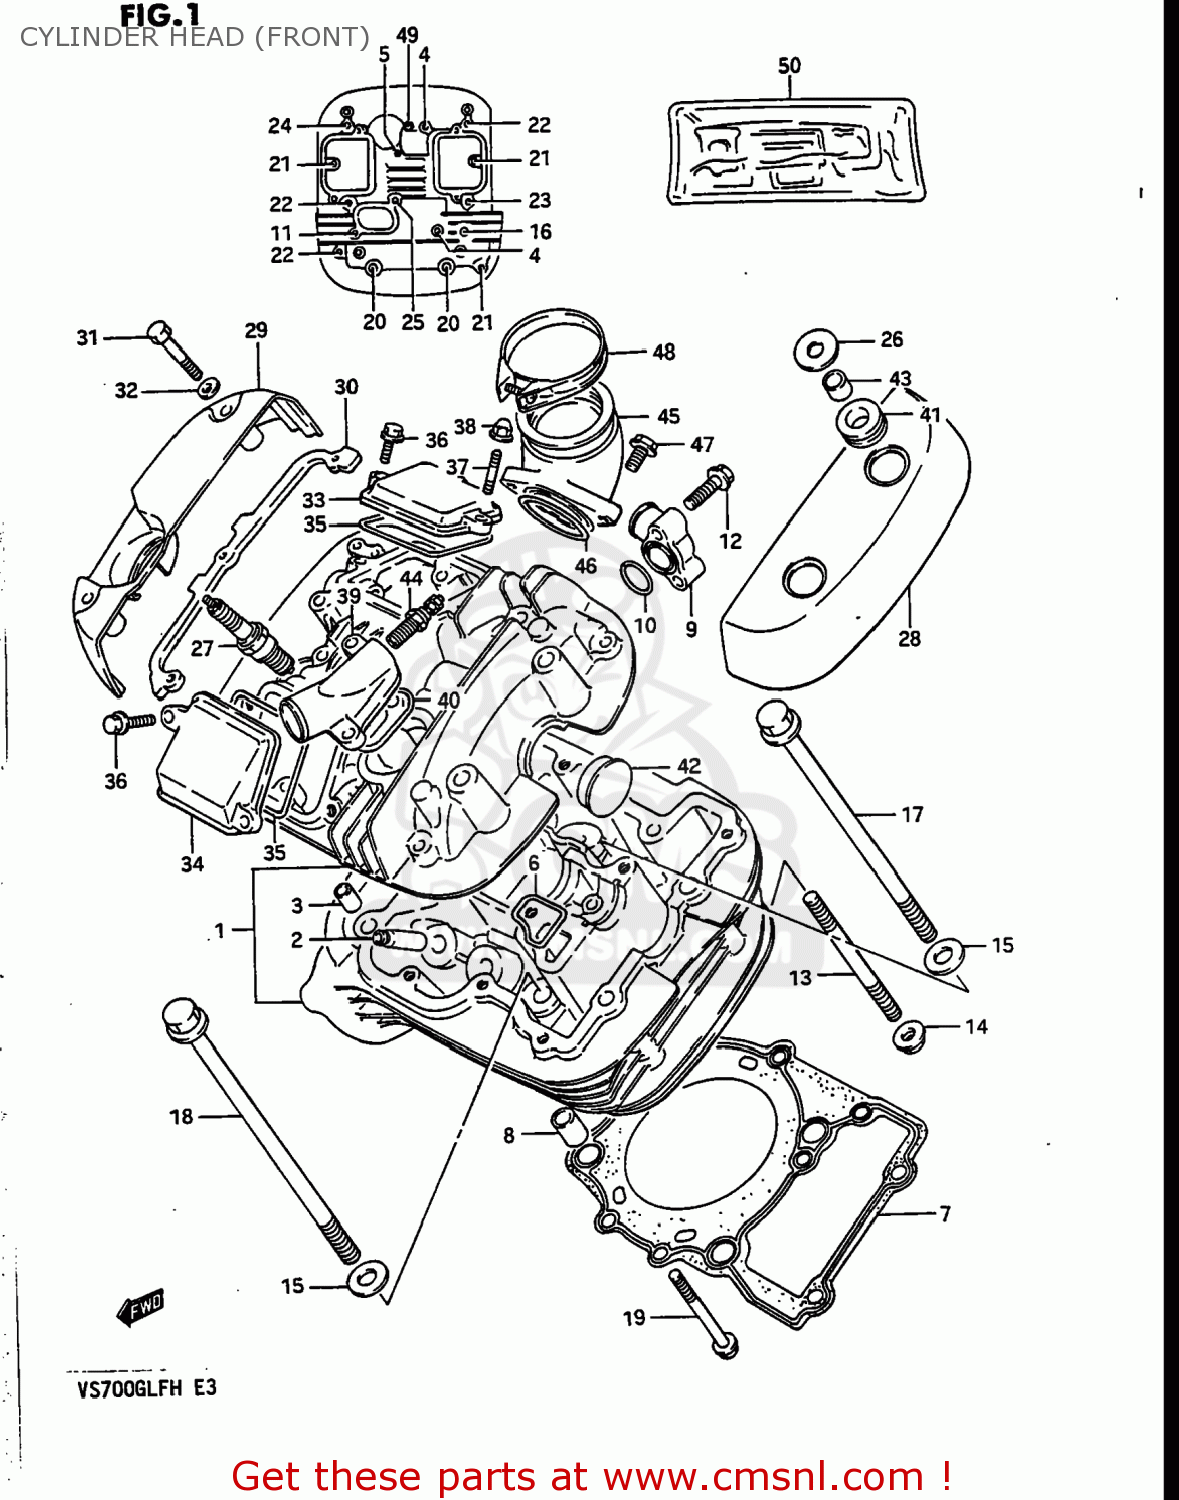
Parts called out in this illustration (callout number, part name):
1	HEAD ASSEMBLY,CYLINDER,FRONT
2	GUIDE,VALVE
3	PIN(11X14)
4	BOLT(6X50)
5	BOLT(6X55)
6	GASKET,CYLINDER HEAD WATER (NAS)
7	GASKET,CYLINDER HEAD FR (MCA)
8	PIN
9	UNION,CYLINDER HEAD WATER
10	O RING(D:2.4,ID:17.8)
11	BOLT,REAR
12	BOLT
13	BOLT,STUD
14	NUT
15	WASHER(10.5X22X2.3)
16	BOLT(8X140)
17	BOLT(10X155)
18	BOLT(10X165)
19	BOLT
20	BOLT(8X245)
21	BOLT
22	BOLT
23	BOLT
24	BOLT
25	BOLT(6X55)
26	WASHER (8.2X24X1.6)
27	SPARK PLUG DP8EA-9
28	CAP,CYLINDER HEAD COVER FR,L
29	CAP,CYLINDER HEAD COVER FR,R
30	CUSHION,FR,R CAP
31	BOLT
32	WASHER
33	CAP,INSPECTION
34	CAP,INSPECTION,EXHAUST
35	GASKET,INSPECTION CAP (NAS)
36	BOLT (6X20)
37	STUD 6X16
38	MOER
39	UNION
40	GASKET,WATER OUTLET UNION (NAS)
41	CUSHION
42	PLUG
43	BUSH
44	GAUGE ASSY,WATER TEMP
45	PIPE,INTAKE
46	O-RING (D:2.4 ID:39.7)
47	BOLT
48	CLAMP,PIPE
49	BOLT
50	GASKET SET (MCA)
